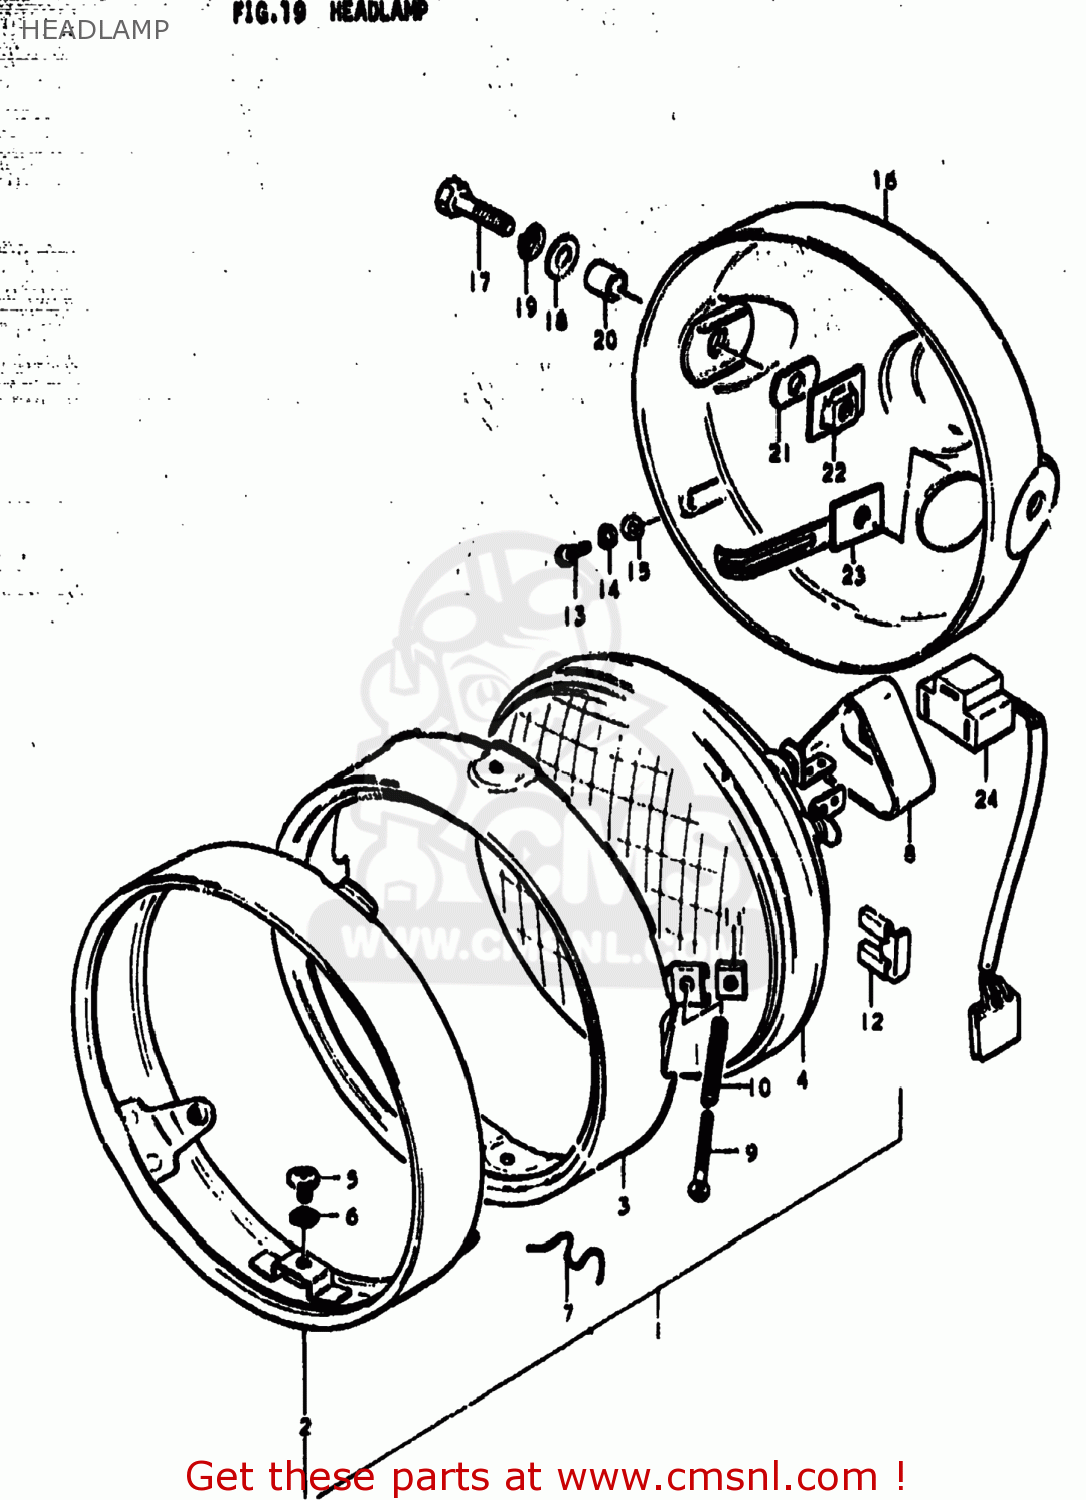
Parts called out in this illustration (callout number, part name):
1	HEADLAMP ASSEMBLY
2	RIM,HEADLAMP
3	RETAINER
4	LAMP UNIT
5	SCREW
6	LOCK WASHER
7	SPRING,HEAD LAMP UNIT
8	COVER
9	SCREW
10	SPRING,HEADLAMP ADJUST
11	NUT
12	COVER, FITING
13	SCREW
14	LOCK WASHER
15	WASHER
16	HOUSING,HEADLAMP
17	BOLT
18	WASHER
19	LOCK WASHER
20	SPACER (8.8X12X7)
21	CUSHION
22	PLATE,HEADLAMP HOUSING
23	PLATE,HEADLAMP HOUSING
24	LEAD WIRE,HEADLAMP
